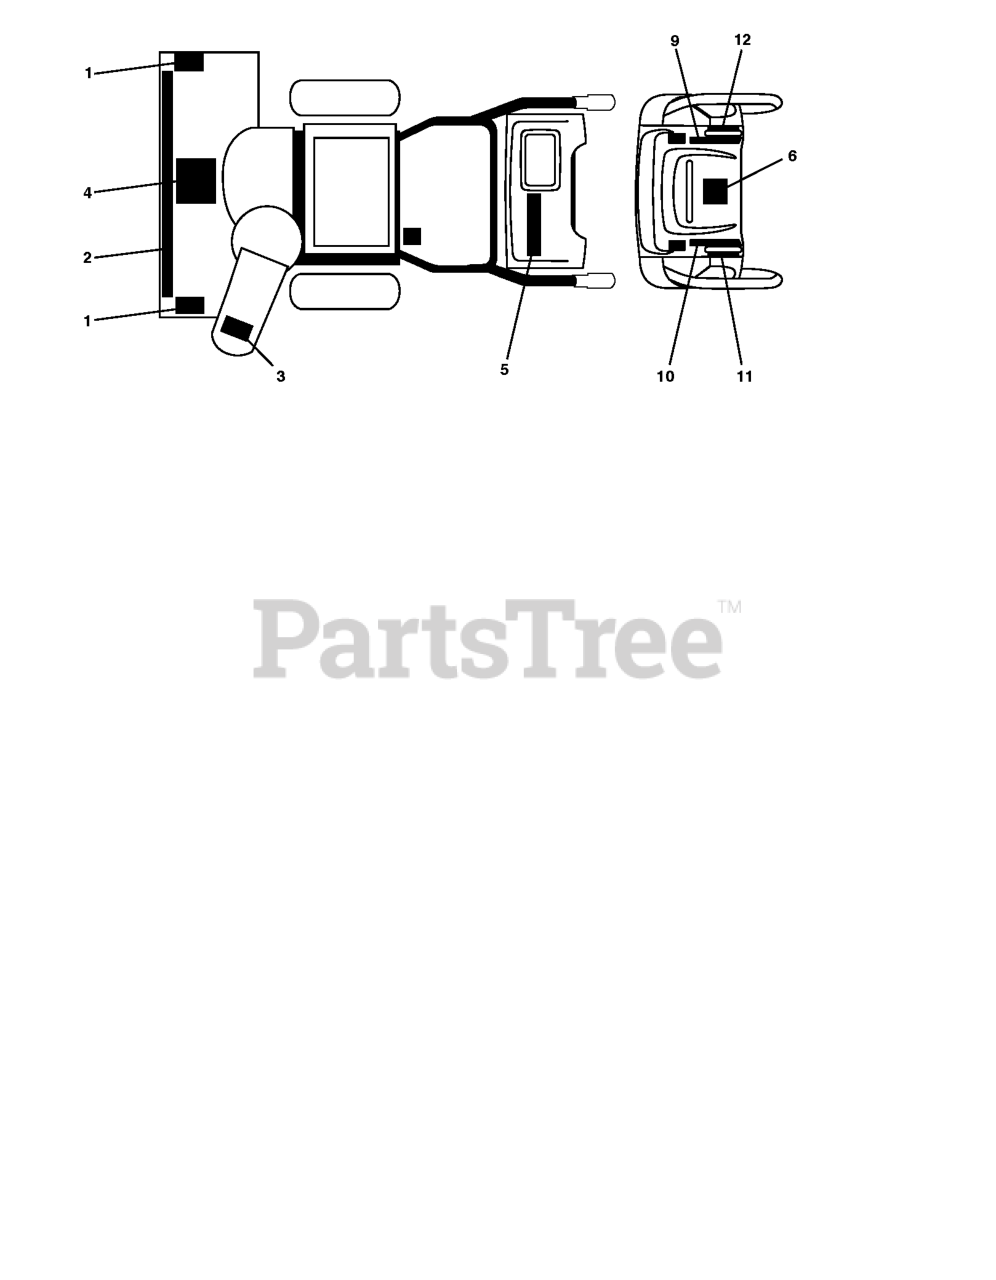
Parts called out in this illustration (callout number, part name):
1	DECAL.SNOWTHR.AUGER
2	DECAL.AUG.HSG.HUSQ.1130SB-XLSB
3	DECAL.SNOWTHR.CHUTE.SAFETY
4	DECAL.SNOWTR.READ.OWN.MAN.E/F
5	DECAL.CONSOLE.HUSQ.
6	DECAL, INSTRUCTION
9	DECAL SPEED CONTROL
10	DECAL, REMOTE DEFLECTOR
11	DECAL POWER STEER
12	3ECAL POWER STEER
